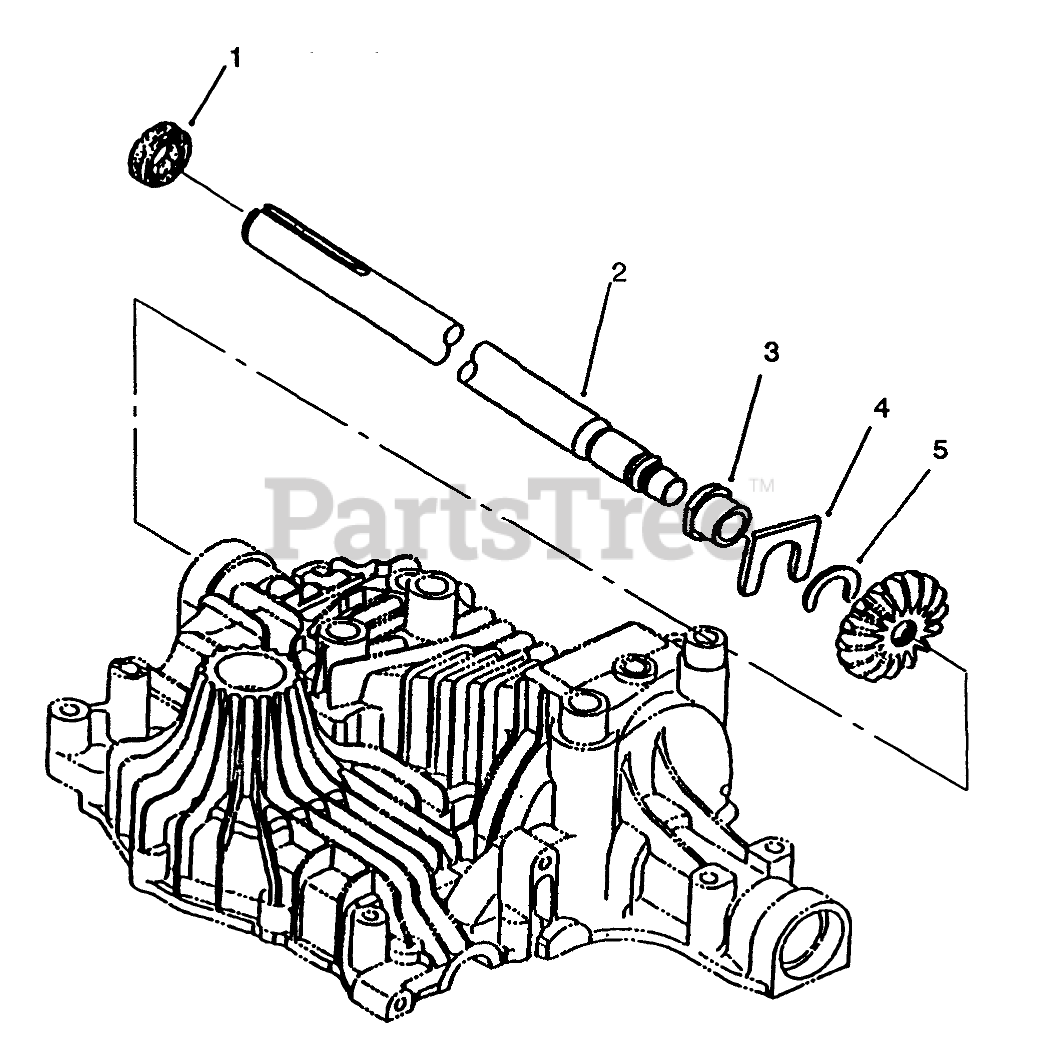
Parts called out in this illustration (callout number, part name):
1	Seal (OnlyOn: 72083, 72043, 72103, 72063)
2	Shaft-Axle Right (Only On: 72083, 72043, 72103, 72063)
3	Bushing (Only On: 72083, 72043, 72103, 72063)
4	Wahser-Thrust (Only On: 72083, 72043, 72103, 72063)
5	Ring (Only On: 72083, 72043, 72103, 72063)
